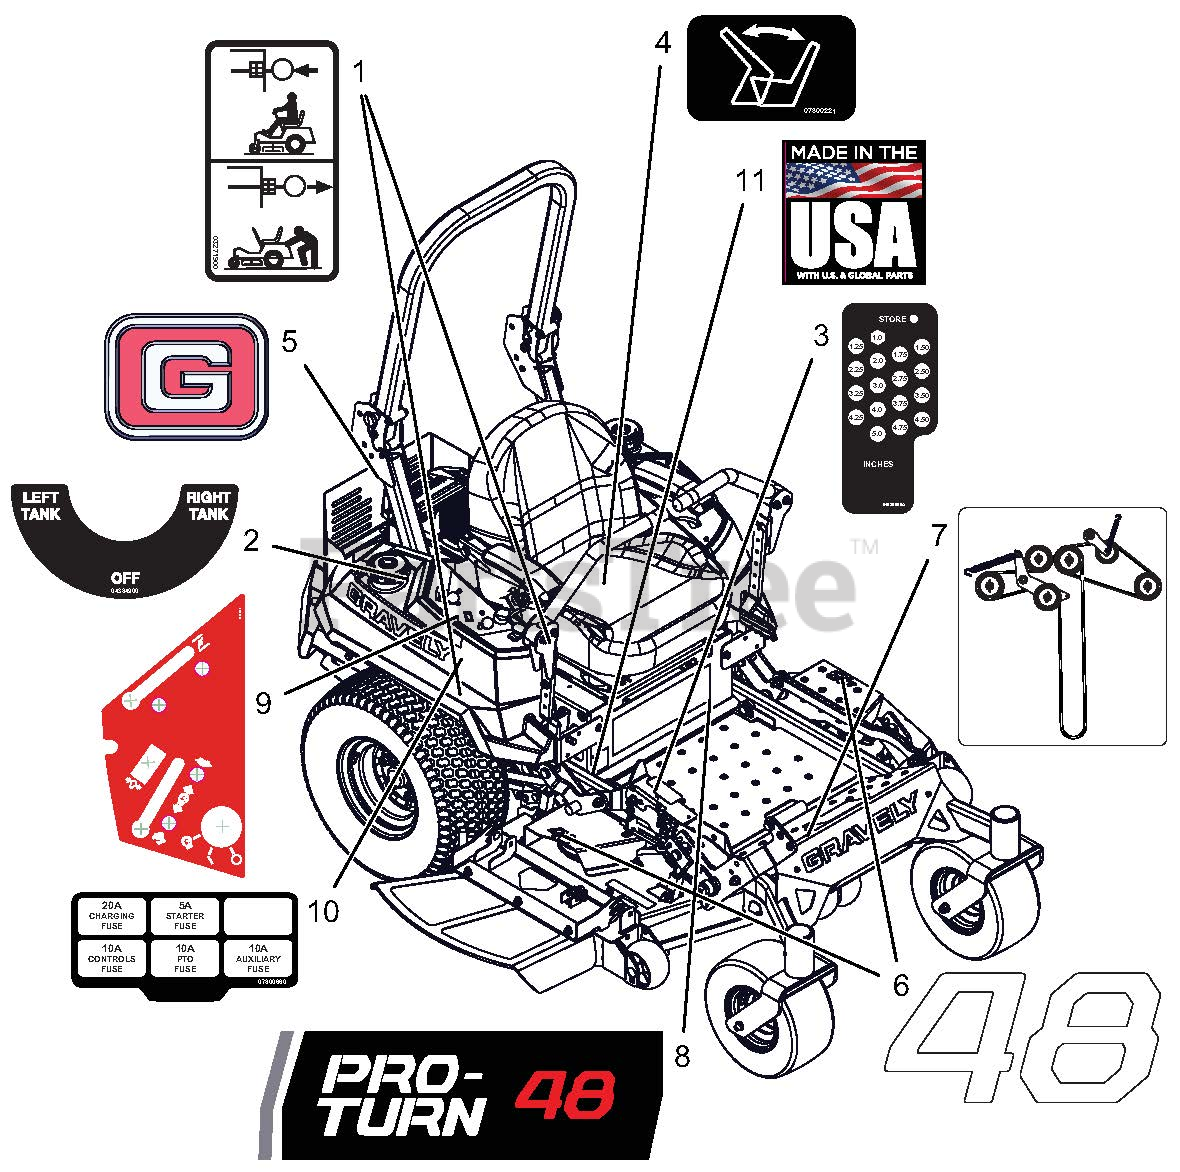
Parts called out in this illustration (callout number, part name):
1	DECAL, TRANSMISSION DISCONNECT
2	DECAL, FUEL VALVE
3	DECAL, HEIGHT OF CUT
4	DECAL - SEAT RELEASE
5	DECAL, GRAVELY BRAND
6	DECAL, 48"
7	DCL,BELT ROUTE-RH V-SIDE IDLER
8	DECAL, PRO-TURN 48
9	DECAL, NON-EFI CONTROL PANEL
10	DECAL, FUSE BLOCK
11	DECAL, MADE IN USA
